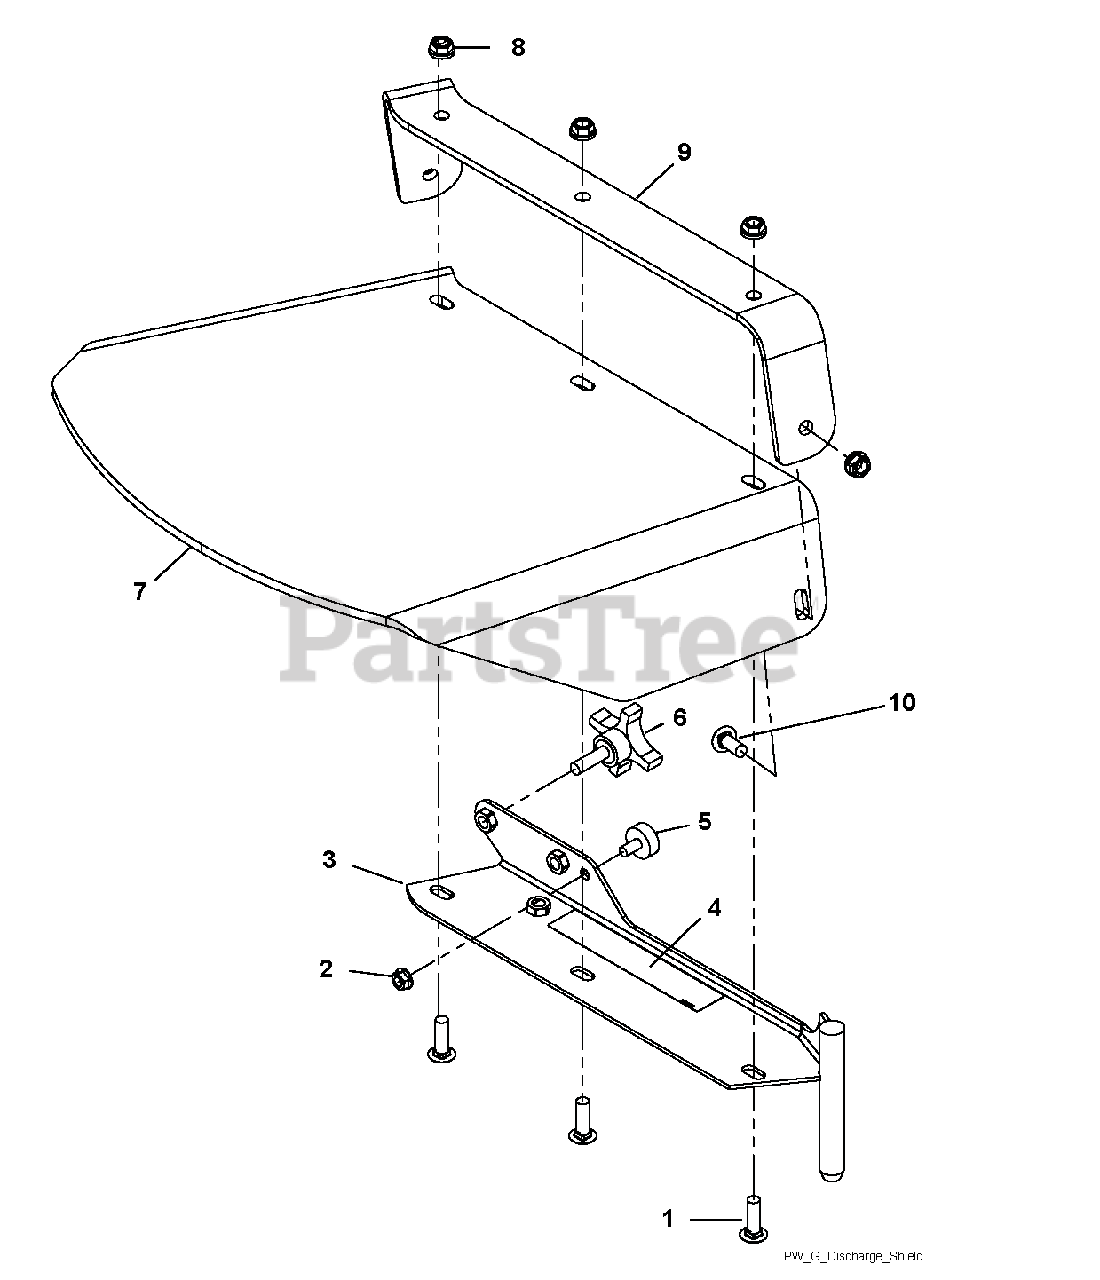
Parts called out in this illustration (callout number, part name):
1	BLT-RHDSSQNK .38-16X1.25 G5YZ
2	LOCKNUT, 5/16-18 WHIZ Y
3	WLDT, DISCHARGE SCAMPER
4	DECAL, WARNING
5	BUMPER, RUBBER
6	KNOB, 3/8 X 1.25 - 4 PRONG
7	SHIELD, WALK RUBBER DISCHARGE
8	NUT-SPNLK-FLG .375-16 YWZC
9	STRAP, WALK RUBBER DISCH GD
10	BLT-RDHDSHSQNK.38-16X1.0 G5YZ
